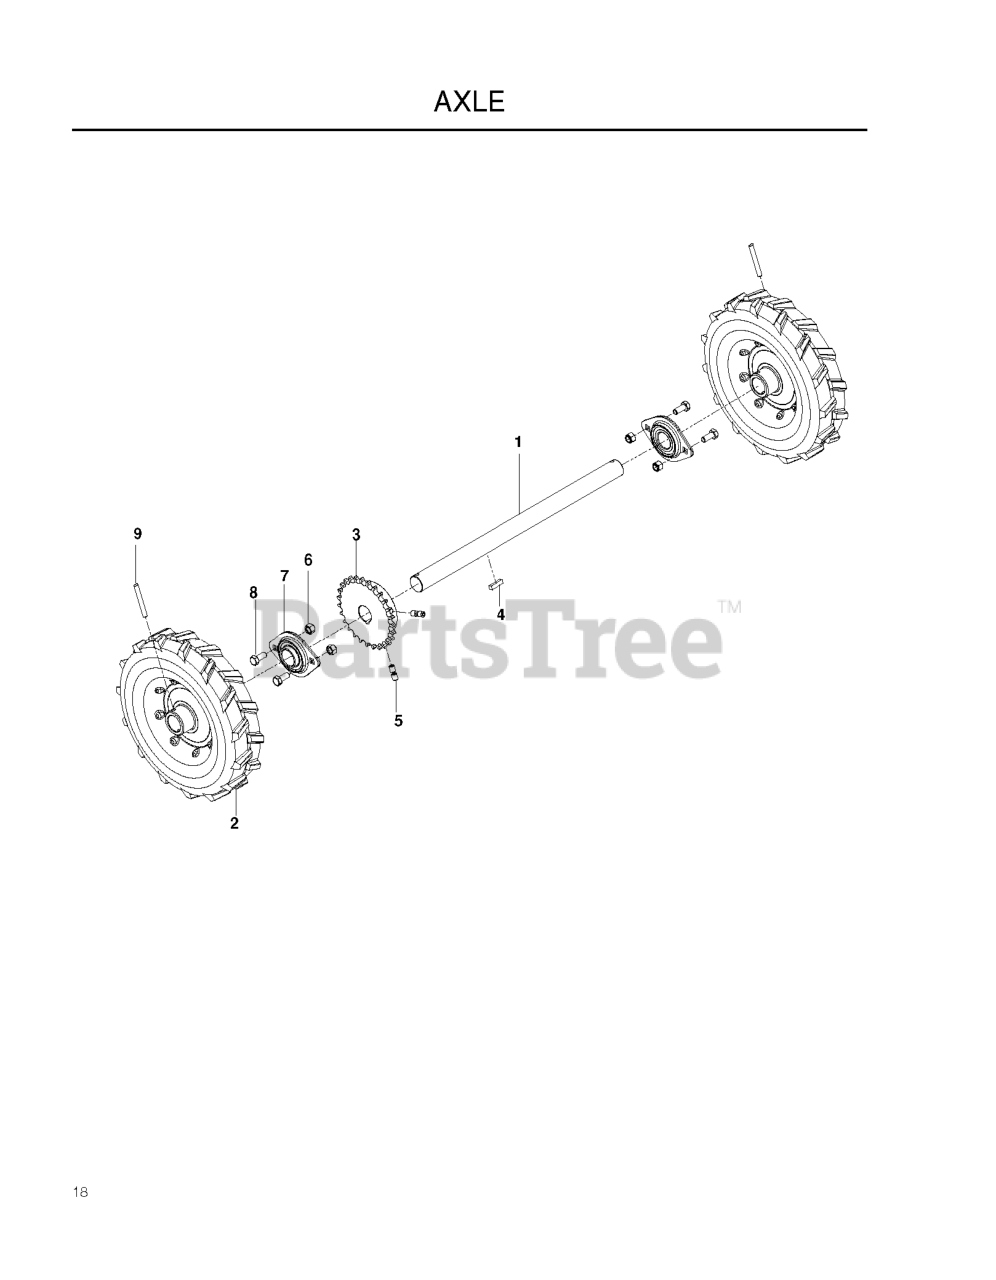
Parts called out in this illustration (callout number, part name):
1	AXLE SC18A
2	KIT WHEEL 10" W/HARDWARE
3	SPROCKET W/KEY, ROTOR 27 TEETH
4	KEY 1/4 SQ X 1.0
5	SET SCREW 5/16 NYLOC
6	NUT 5/16 NYLOC
7	FLANGE BEARING ZINC PLATED 1"
8	HCS 5/16C X 3/4
9	SPIRAL PIN 1/4 X 1-1/2
